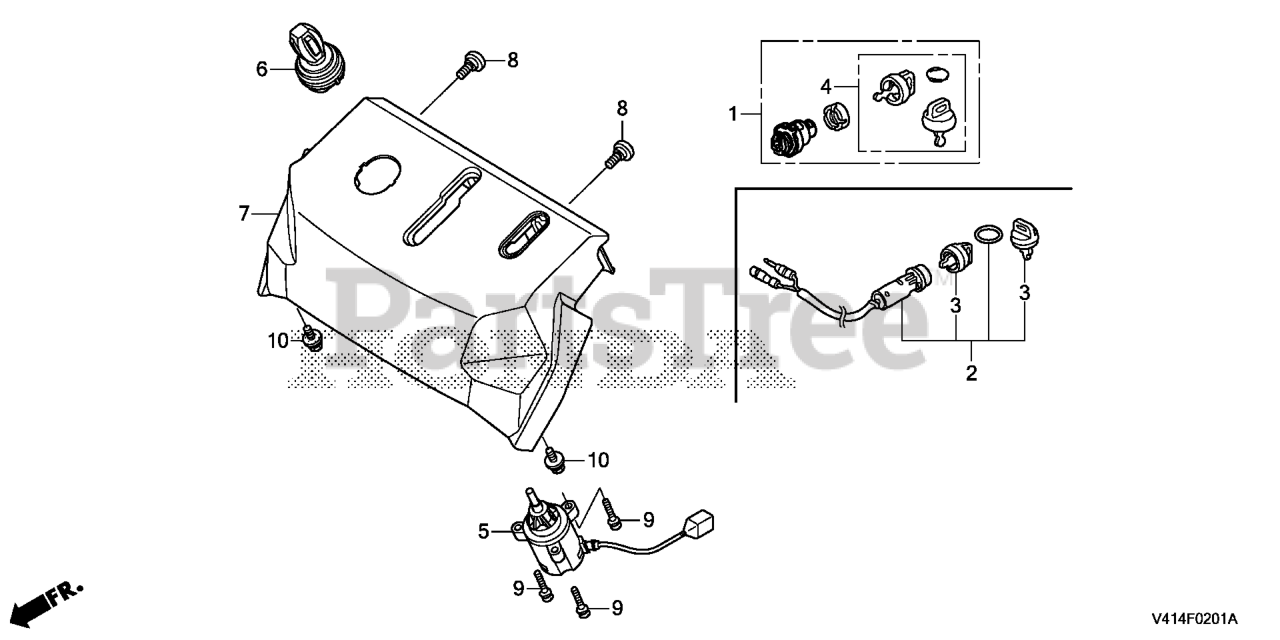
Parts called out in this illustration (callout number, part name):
1	SWITCH ASSY., COMBINATION
4	KEY ASSY., COMBINATION SWITCH
5	SW CHUTE CNTRL
6	BOOT, RUBBER
7	PANEL, CONTROL *NH296* (ALPS GRAY)
8	BOLT, CHUTE SETTING
9	BOLT-WASHER (5X20)
10	BOLT-WASHER (5X12)
